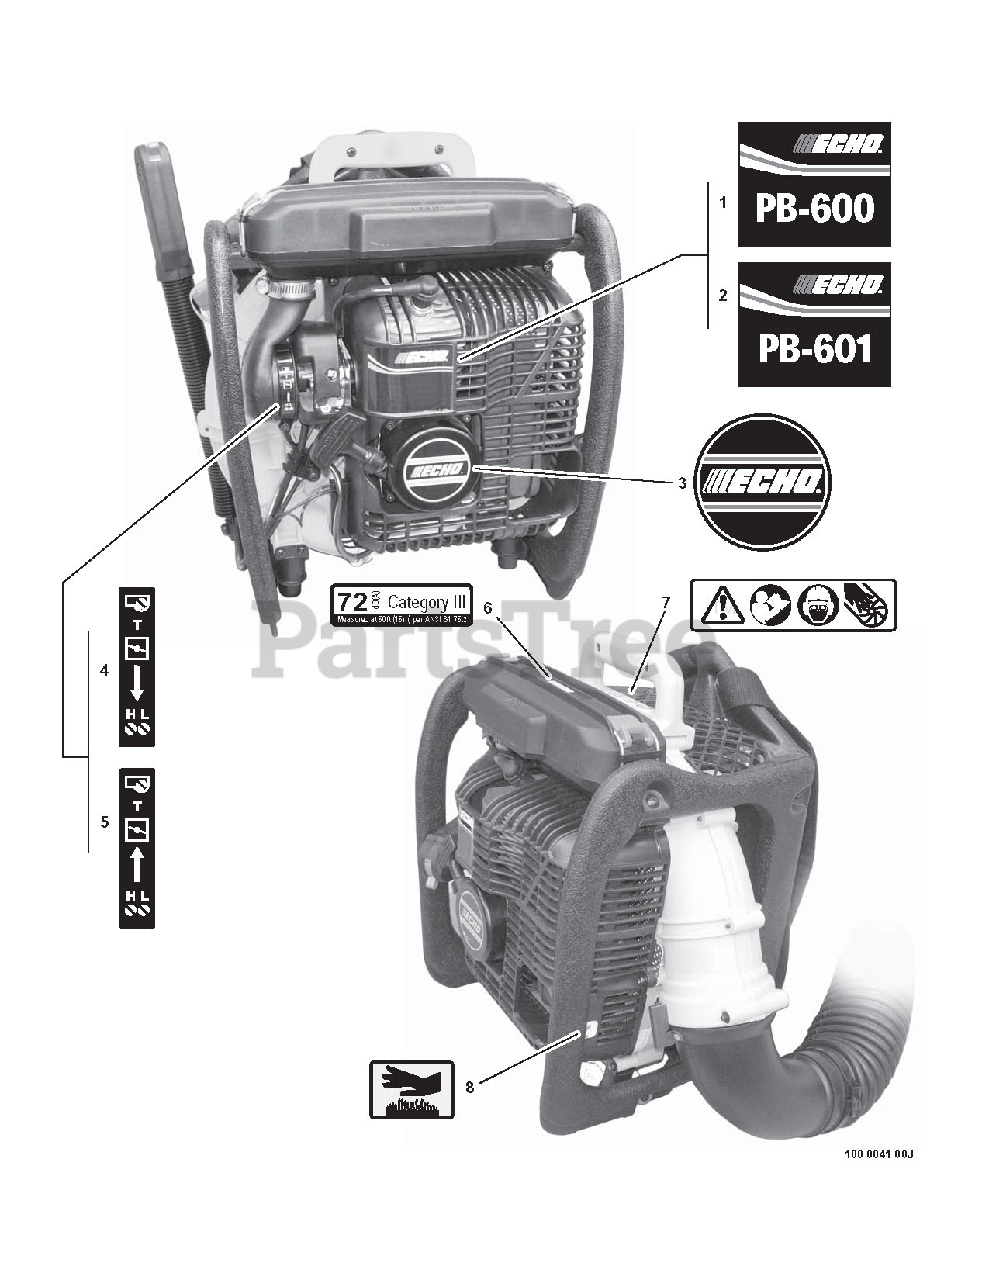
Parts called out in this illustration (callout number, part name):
1	LABEL - MODEL PB-600
2	LABEL - MODEL PB-601
3	LABEL - ECHO
4	LABEL - CHOKE
5	LABEL - CHOKE
6	LABEL - NOISE 72dB(A) CAT III
7	LABEL - CAUTION
8	LABEL - HOT SURFACE
